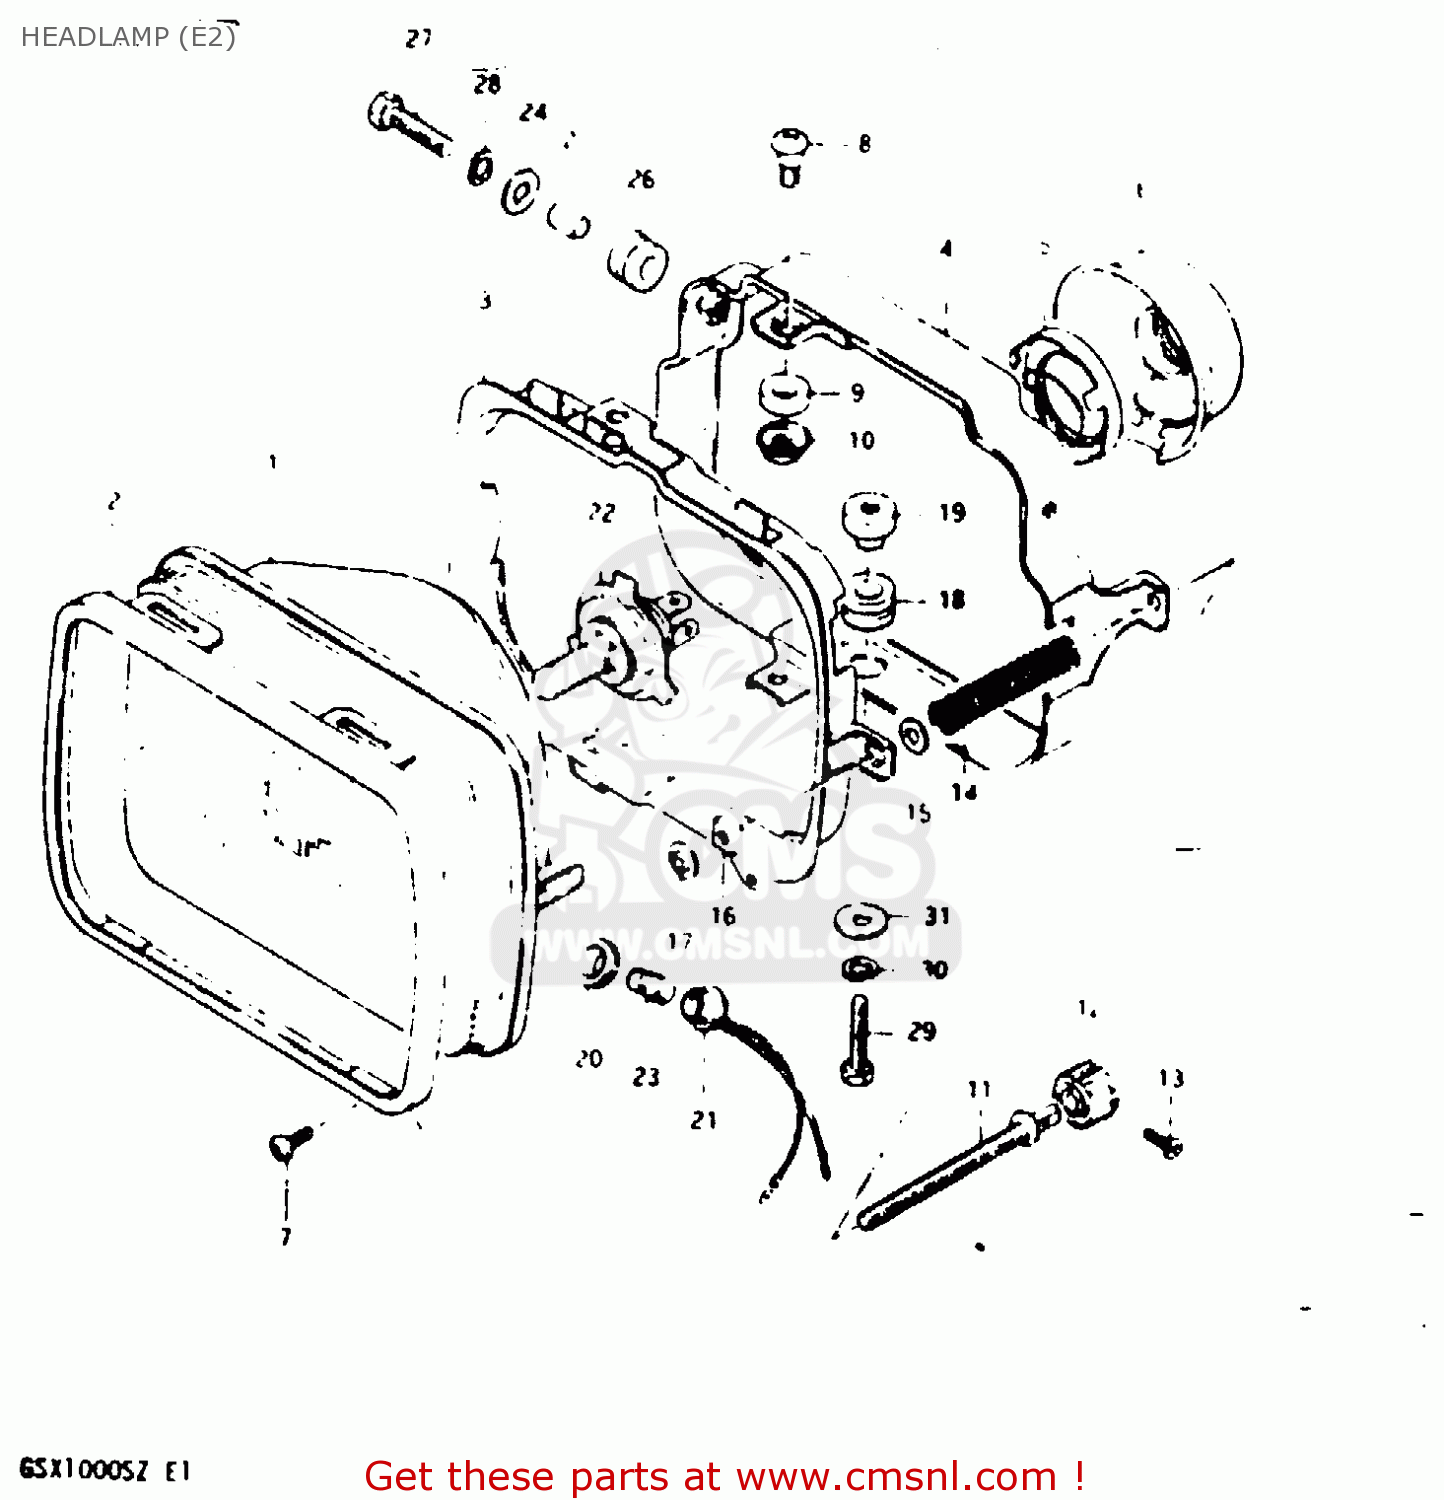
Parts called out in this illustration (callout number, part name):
1	UNIT
2	RETAINER
3	RING,MOUNTING
4	HOUSING
5	HOLDER, BULB
6	COVER,HEADLAMP SOCKET
7	SCREW
8	SCREW
9	SPACER
10	NUT,ADJUSTING
11	SCREW,ADJUSTING
12	KNOB,ADJUSTER
13	SCREW
14	SPRING
15	WASHER
16	NUT
17	NUT,HEADLAMP ADJUSTER
18	CUSHION
19	NUT
20	JOINT,RUBBER
21	SOCKET
22	BULB(12V60/55W,H4)
23	BULB(12V4W)
24	WASHER
25	SPACER (6.1X8X9.5)
26	CUSHION
27	BOLT
28	LOCK WASHER
29	SCREW(6X20)
30	LOCK WASHER
31	WASHER
